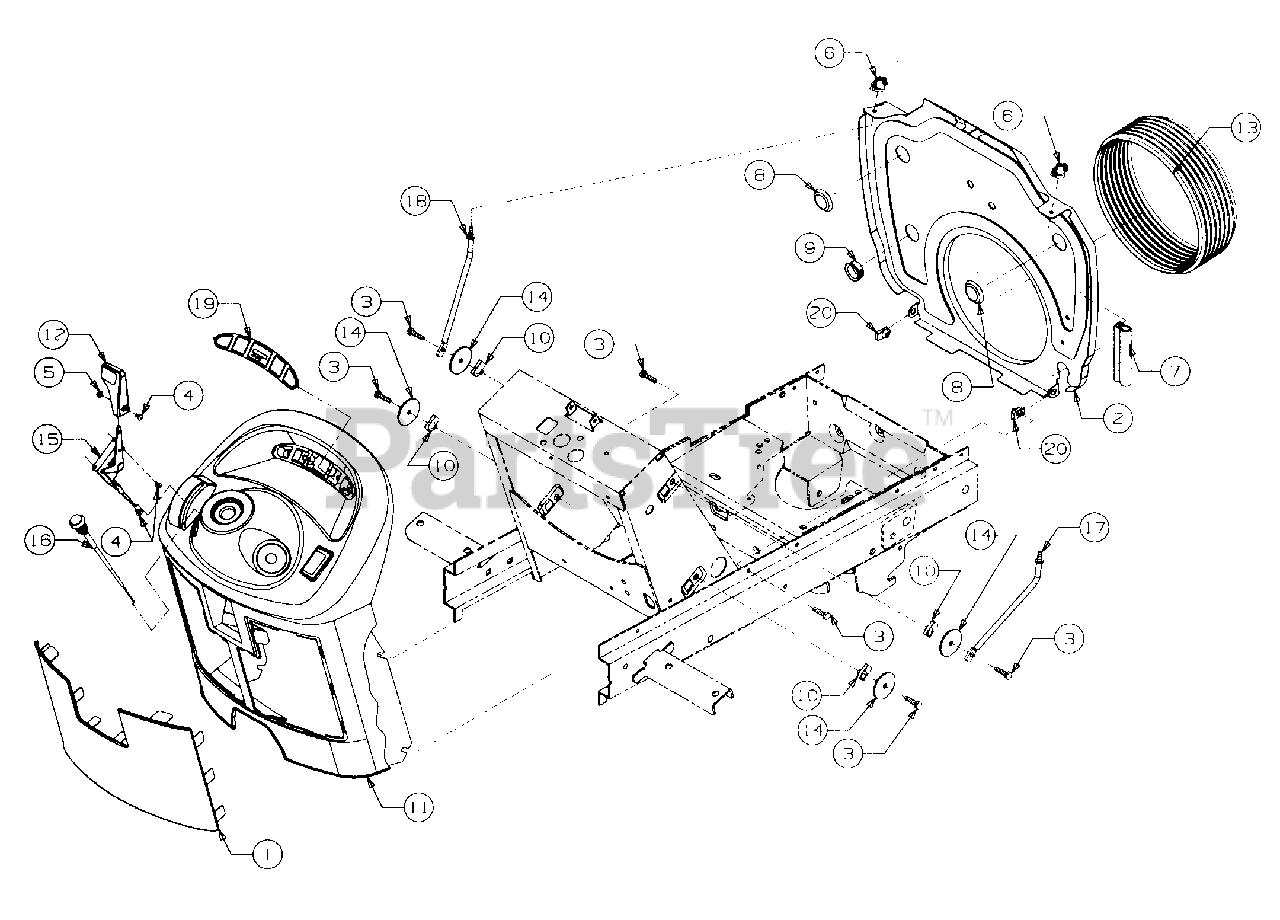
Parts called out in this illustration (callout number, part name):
2	Bulkhead, Lower
3	Screw, Hex Cap, 1/4-20 x 1.0 Lg GR2
4	Screw, Cross Rec Truss Hd #8-32 x .38 Lg
5	Nut, #8-32
6	Nut, Wing w/Bell Washer, 1/4-20
7	Seal, Push-on Trim, 14" Lg
8	Plug, Button, 1.12 Dia
9	Bushing, Snap, 7/8 ID
10	Nut, U-Clip, 1/4-20
11	Panel, Dash
12	Knob, Throttle
13	Boot, Intake
14	Washer, Flat, .285 x 1.75 x .10 Thk
15	Control, Throttle
16	Control, Choke
17	Rod, RH Mounting
18	Rod, LH Mounting
19	Label, Dash
20	Nut, U-Type Speed, 1/4-20
